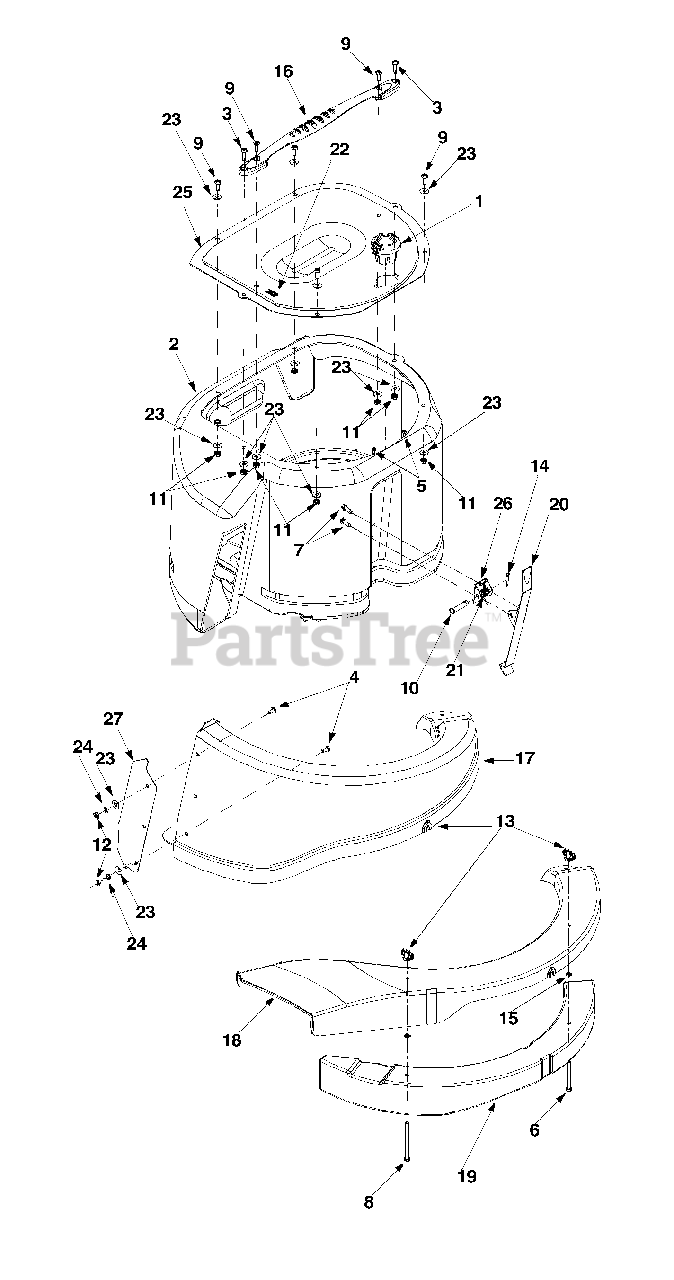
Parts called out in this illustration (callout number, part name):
1	Flow Indicator Assembly
2	Grass Bag Assembly
3	Machine Screw 1/4-20 x 1.0
4	Machine Screw 1/4-20 x 0.5"
5	Hex Screw #10-16 x 0.5"
6	Hex Screw 1/4-20 x 2.75"
7	Self-Tapping Screw 1/4-20 x 0.75"
8	Hex Screw 1/4-20 x 3.75"
9	Machine Screw 1/4-20 x 0.75"
11	Hex Sems Nut 1/4-20
12	Jam Nut
13	Wing Nut
15	Speed Nut
17	Discharge Chute: Grass Bag
18	Side-Discharge Chute
19	Mulching Plug
20	Bag Release Lever
21	Torsion Spring
24	Lock Washer
